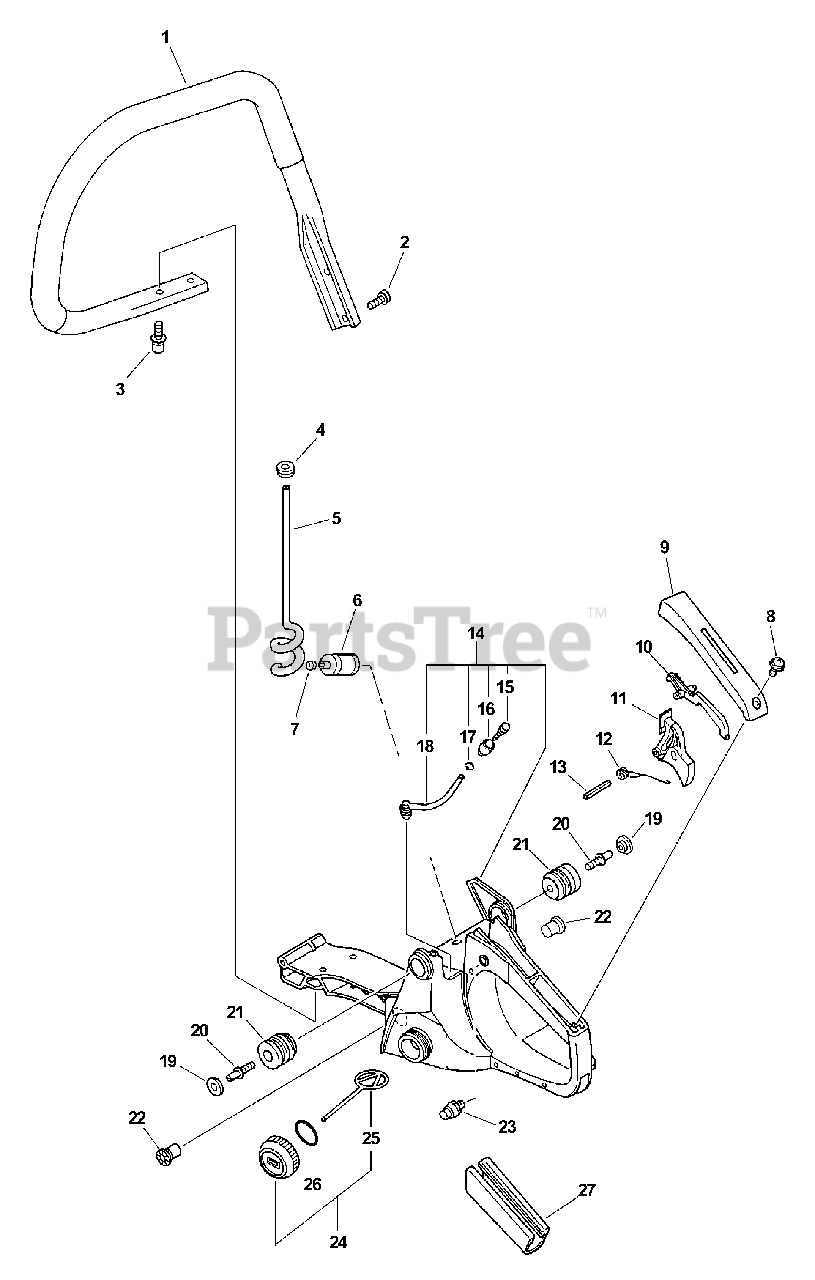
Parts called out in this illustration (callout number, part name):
1	HANDLE - FRONT
2	SCREW - 5X20 -- TAPPING
3	SCREW - 5X16
5	PIPE, FUEL - SPIRAL
6	FILTER, FUEL
7	CLIP - 6.5
8	SCREW - 4X14
9	COVER, HANDLE
10	LEVER, TRIGGER LOCKOUT
11	TRIGGER, THROTTLE
12	SPRING, TRIGGER
13	PIN - SPRING -- 4X30
14	HANDLE ASSY - REAR
15	VENT, FUEL TANK
16	COVER, VENT
17	CLIP - 6.5
18	PIPE - VENT
19	CAP, CUSHION
23	LATCH, THROTTLE
24	CAP ASSY - ORANGE
25	CONNECTOR, CAP
26	O-RING - 22
27	GRIP, HANDLE
